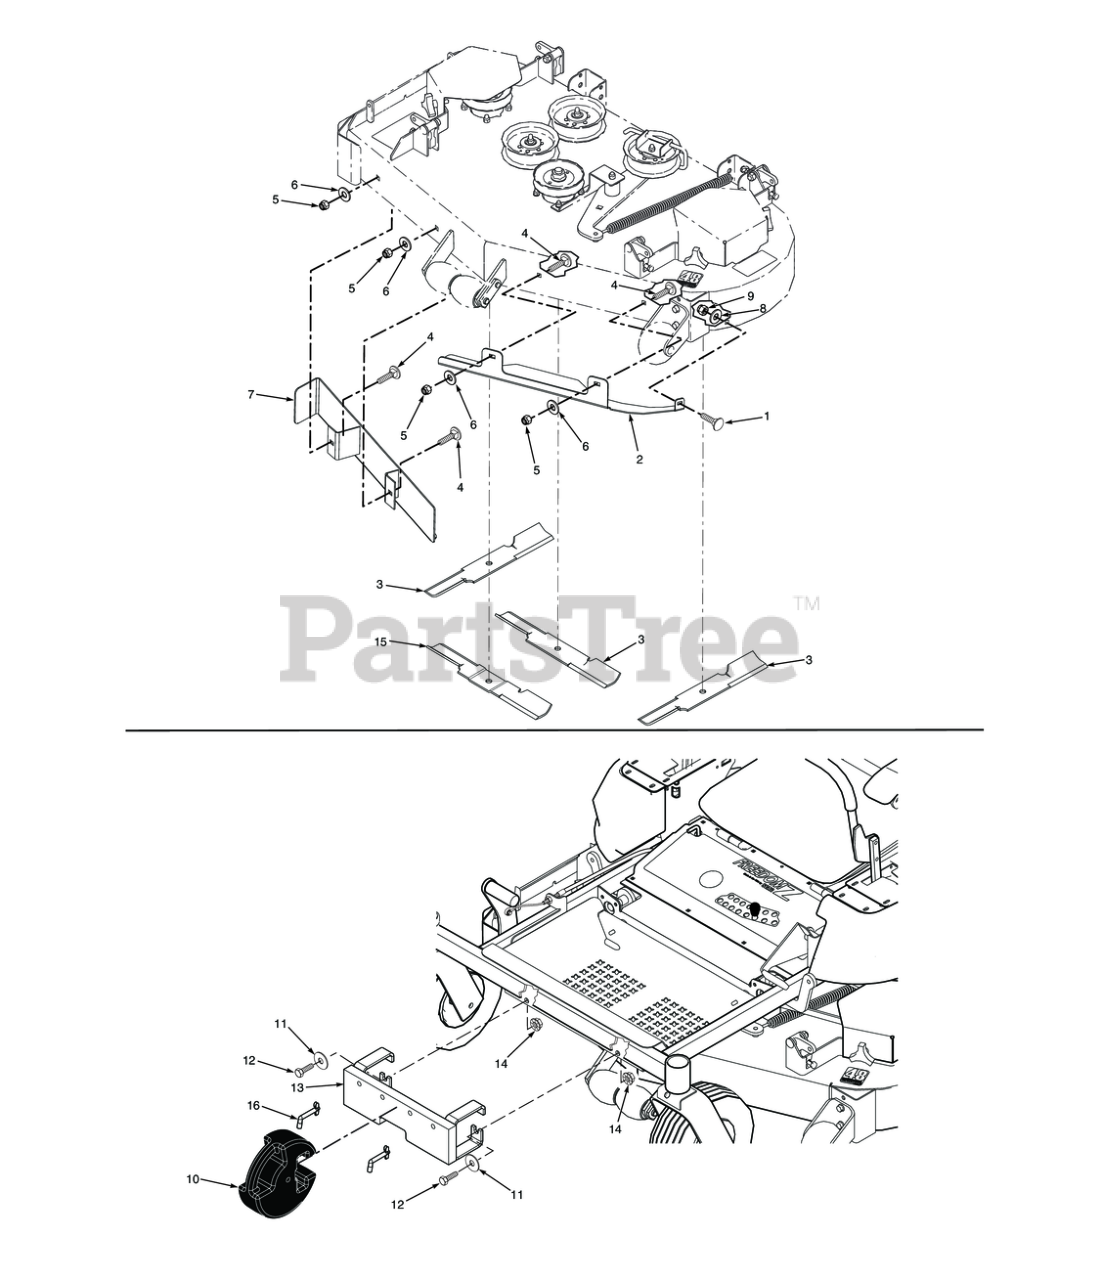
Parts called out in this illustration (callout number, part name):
1	Bolt, 5/16-18 x .75 RHSN Carriage
2	Baffle, LH - 42" Deck
2	Baffle, LH - 48" Deck
2	Baffle, LH - 52" Deck
2	Baffle, LH - 61" Deck
3	Cutter Blade 18" Hi Lift (marbane)
3	Cutter Blade, High Lift (42" Deck)
3	Cutter Blade 16-1/2" Hi Lift (marbane)
3	Cutter Blade, High Lift (61" Deck)
4	Carriage Bolt, 3/8-16 x 1.0"
5	HEX NUT, ELASTIC STOP LOCK, 3/8-16
6	Flat Washer, 1/2 (.562 x 1.375 x .109)
7	Baffle Weldment,RH - 36" Deck
7	Baffle Weldment, RH - 42" Deck
7	Baffle Weldment, RH - 48" Deck
7	Baffle, Weldment, RH - 52" Deck
7	Baffle, Weldment, RH - 61" Deck
8	Flatwasher, 5/16-.344 x .688 x .065 (48V / 52V)
9	Nut, Center Lock, 5/16-18(32)
10	Weight
11	Flat Washer, 1/2 (.562 x 1.375 x .109)
12	Bolt, Hex Head 1/2-13 x 1-1/4"
13	Support Weldment, Weight Mounting
14	Nut, Hex Serrated Flange 1/2-13
15	Cutter Blade, Cross - 36" & 52" Deck
15	Cutter Blade, Cross - 42" Deck
15	Cutter Blade, Cross - 48" Deck
15	Cutter Blade, Cross - 61" Deck
16	Pin, Weight Retention
